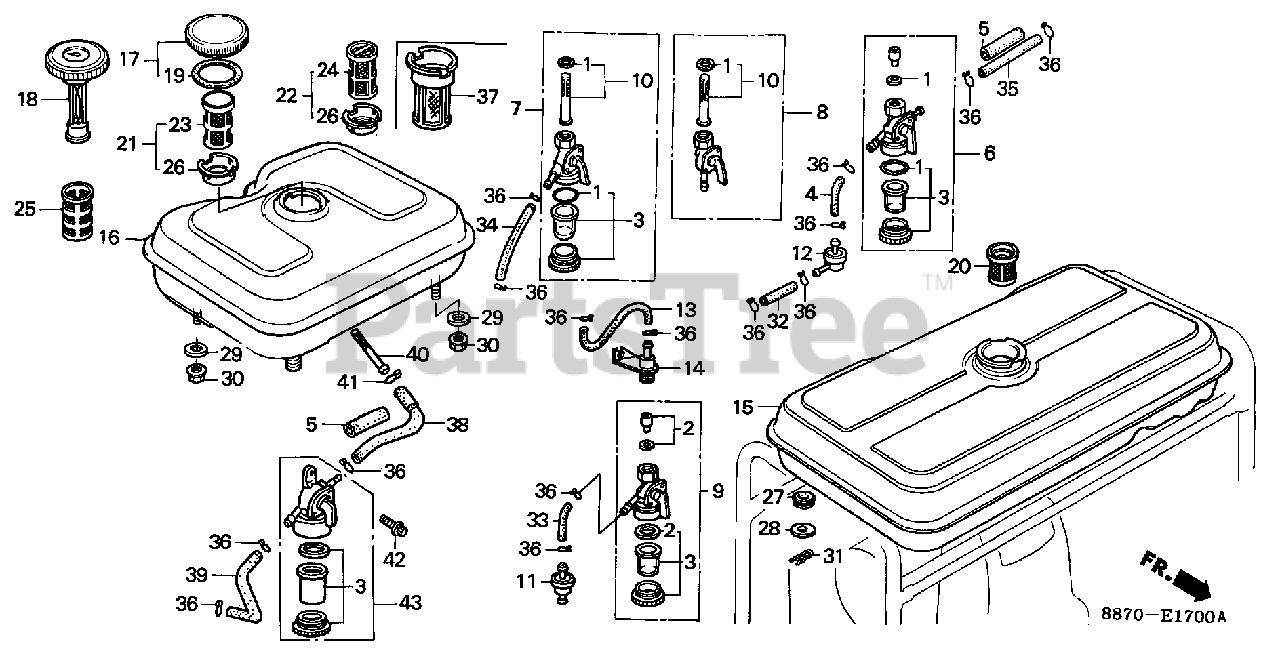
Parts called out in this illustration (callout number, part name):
1	GASKET SET, PETCOCK
3	CUP, FUEL STRAINER
3	CUP SET, FUEL STRAINER
7	PETCOCK ASSY.
10	SCREEN SET
16	TANK, FUEL
16	TANK, FUEL *NH31* (MCKINLEY WHITE)
17	CAP, FUEL FILLER (BLACK)
17	CAP, FUEL FILLER
17	CAP, SUB-TANK
18	GAUGE, FUEL (ENGLISH) Use up to Engine SN 2014339.
18	GAUGE, FUEL (ENGLISH) Use from Engine SN 2014340.
19	GASKET, FUEL FILLER CAP
19	GASKET, FUEL FILLER CAP (39X58X3)
21	FILTER, FUEL
23	FILTER, FUEL
26	HOLDER, FUEL FILTER
30	NUT, FLANGE (6MM)
34	BULK HOSE, FUEL (4.5X3000) (4.5X70)
36	CLIP, TUBE (B8)
